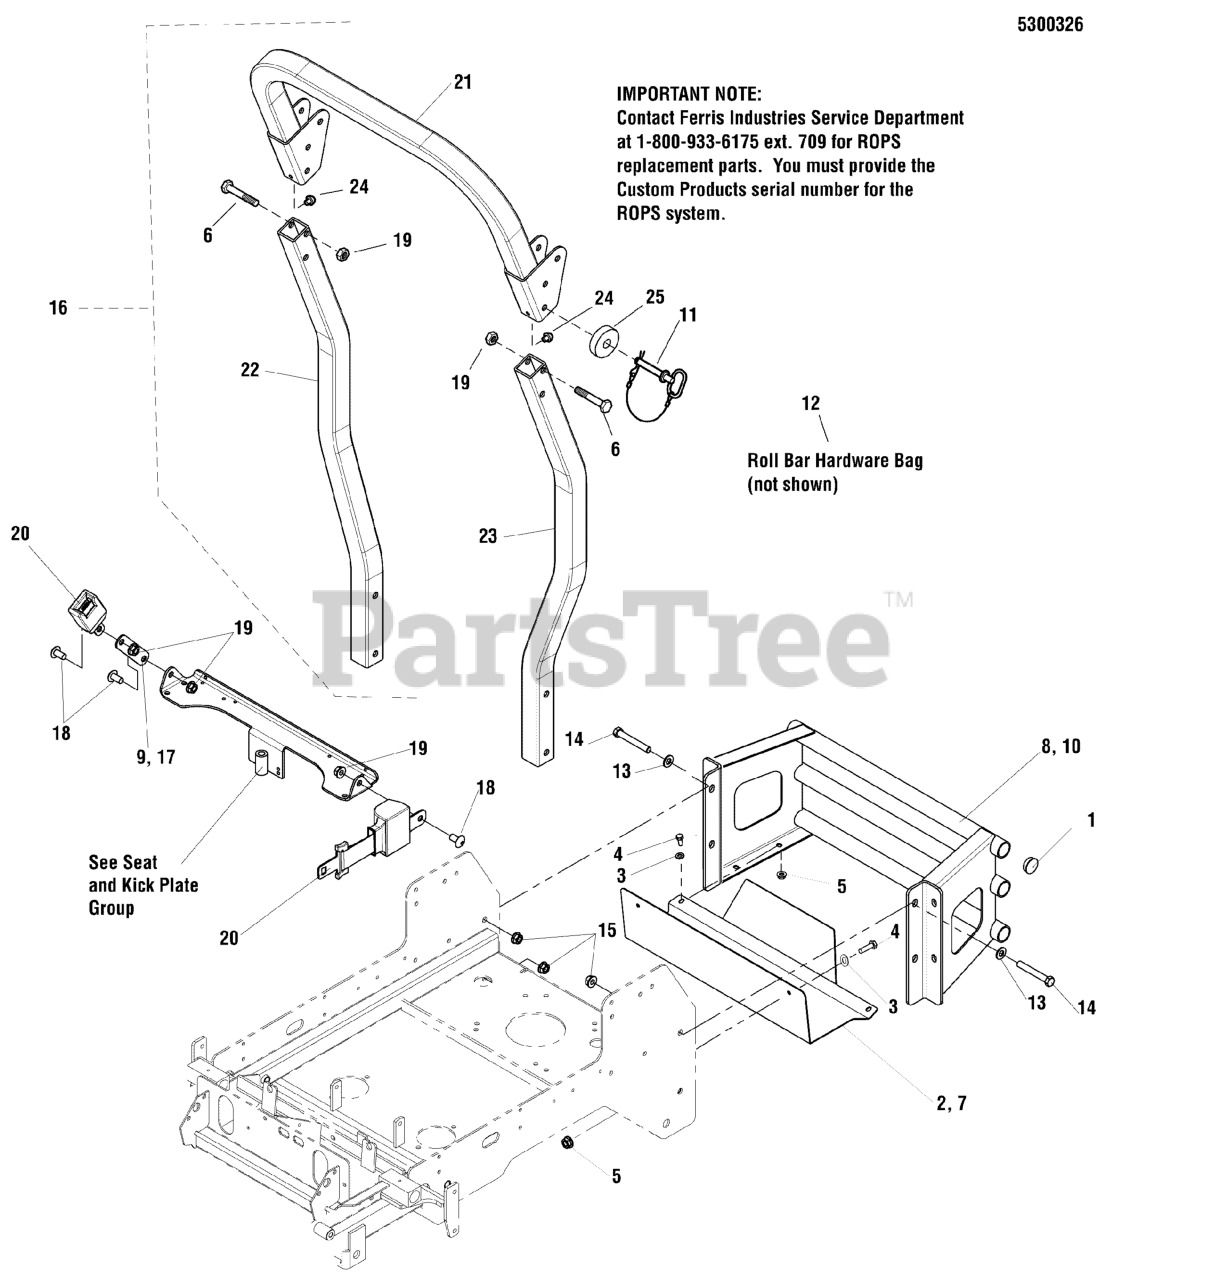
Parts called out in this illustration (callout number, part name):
1	PLUG, PANEL, 1.25 - BLACK
2	HEAT SHIELD - RED MODEL
3	WASHER, 5/16" GD.9 FLAT
4	BOLT, 5/16-18 X 3/4 GD5
5	NUT, 5/16-18 HEX NYLOCK FLANGE
6	*BOLT
7	HEAT SHIELD - ORANGE MODEL
8	WELD, BUMPER, ORANGE MODEL
9	EXTENSION, SEAT BELT - BLK
10	WELD, BUMPER - RED MODEL
11	PIN, HITCH, BLACK W/ PLASTIC LANYARD
12	ROLL BAR HARDWARE BAG
13	WASHER, 1/2 SAE
14	BOLT, 1/2-13 X 3-1/4, HEX HD, GD5, CZ (SV)
15	NUT, Hex Flange, Nylock, 1/2-13
16	ROPS (Call 1-800-933-6175 ext. 2193 if replacing a ROPS)
17	EXTENSION, SEAT BELT - BLK
18	SCREW, 1/2-13 X 1.00, SHCS
19	*NUT
20	SEAT BELT, RETRACTING - ASSM
21	ROLL BAR TOP LOOP
22	ROLL BAR POST, RH
23	ROLL BAR POST, LH
24	RUBBER BUMPER
25	RUBBER WASHER
